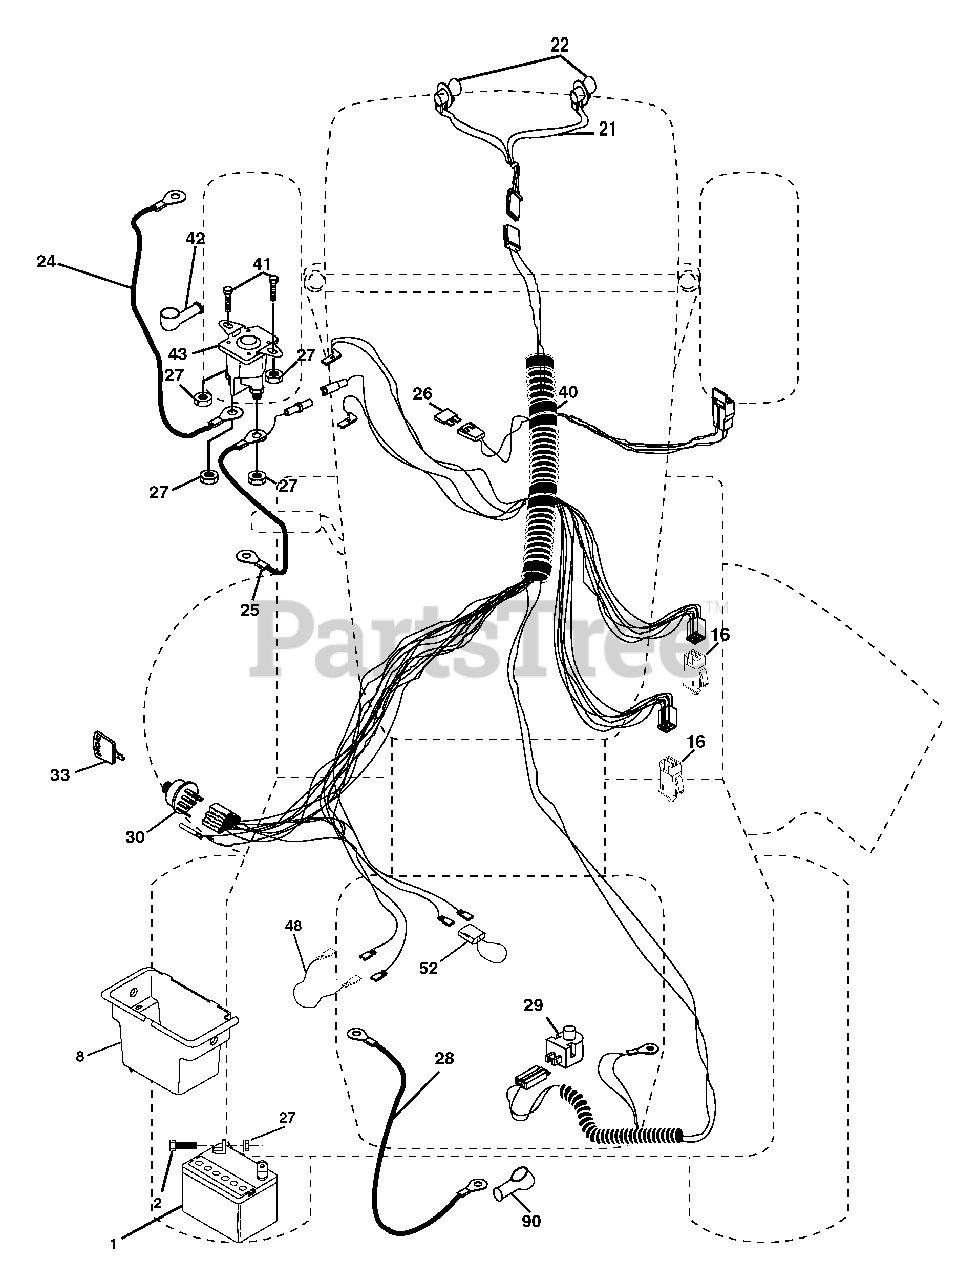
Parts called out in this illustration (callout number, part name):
1	Battery
2	Bolt Hex Hd 1/4-20 Unc x 3/4
8	Box Battery Fender
16	Switch, Interlock
21	Harness Asm Light W/4152j
22	Bulb Light #1156
24	Cable Battery 6 Ga 11" red
25	Cable Battery 6 Ga w/16 wire red
26	Fuse 20 AMP
27	Nut, Keps Hex 1/4-20 Unc
28	Cable Ground 6 Ga 12" black
29	Switch Plunger Nc Gray
30	Switch Ign
33	Key Ign.
40	Harness Ign
41	Bolt Blk. Fin Hex 1/4-20 Unc x 1/2
42	Cover Terminal Red
43	Solenoid
48	Adapter Ammeter
52	Protection Wire Loop
90	Cover Battery Terminal
